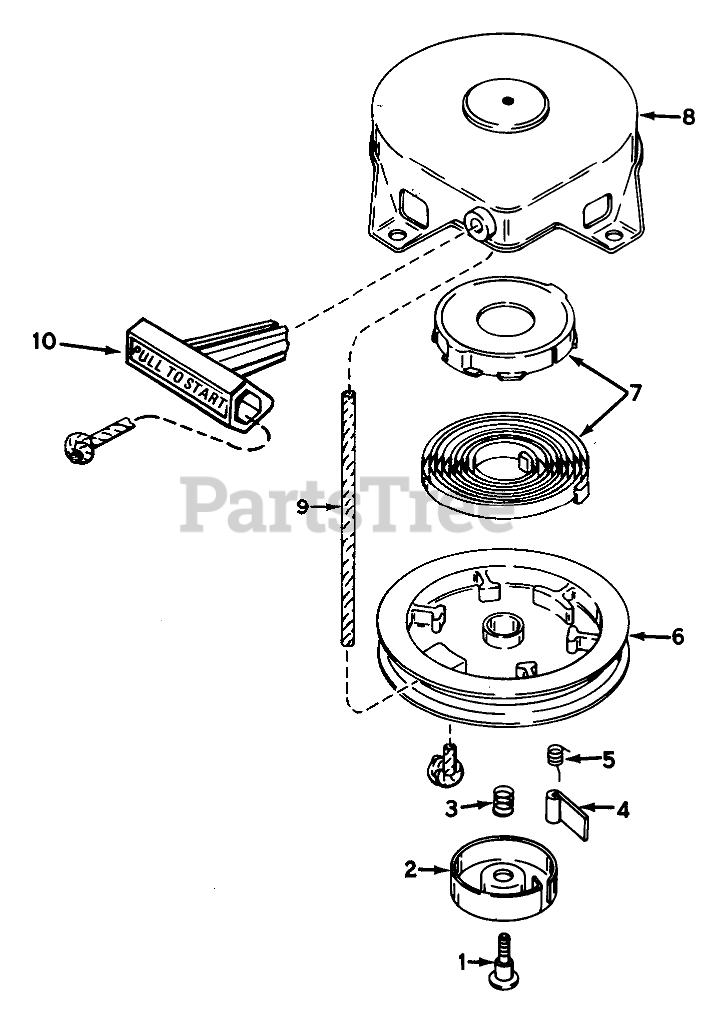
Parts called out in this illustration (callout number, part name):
2	Retainer
3	Spring-Brake
4	Dog-Starter
5	Spring-Dog
7	Spring & Keeper Assy
8	Housing-Starter
9	Rope-Starter (98 cut to length)
10	Handle-Starter
